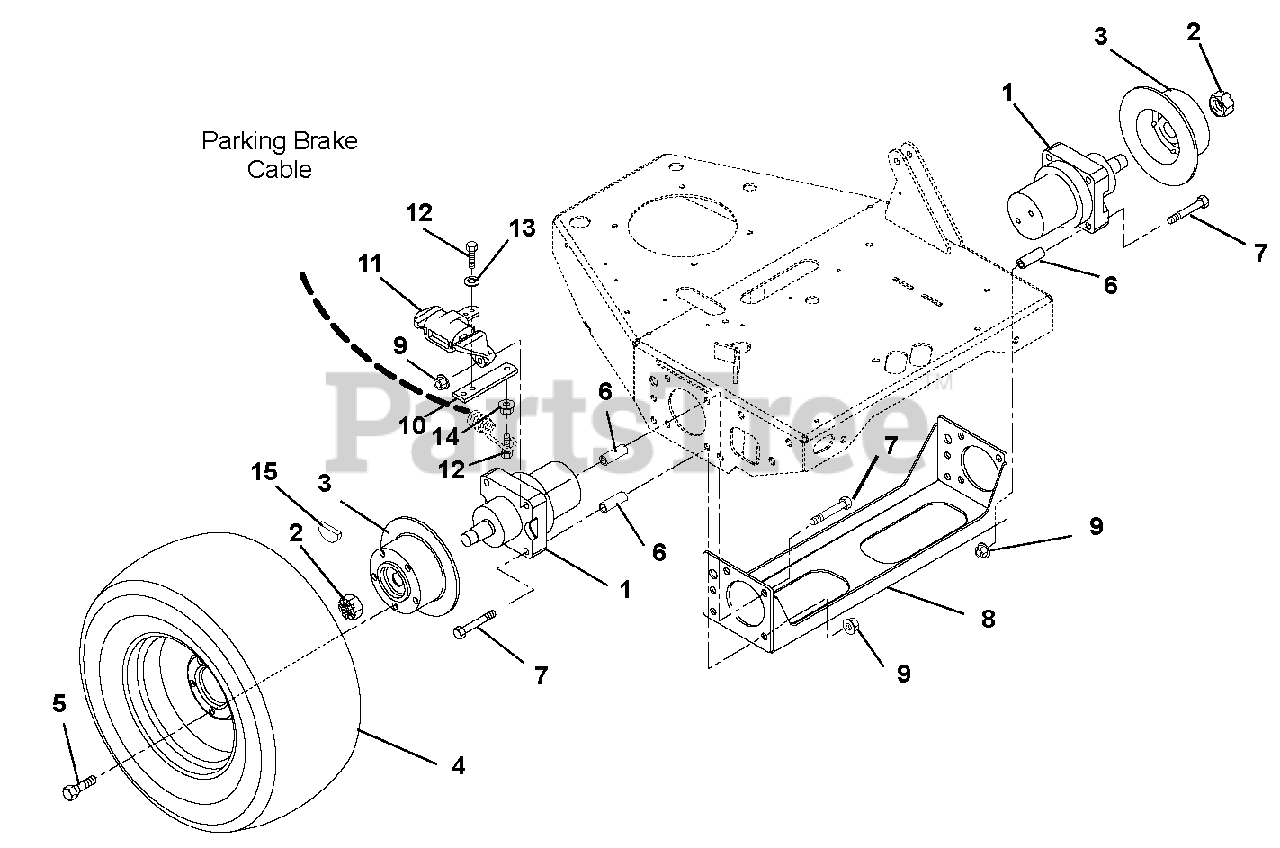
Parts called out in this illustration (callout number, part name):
1	Motor, Hydraulic Wheel (Includes 2)
2	Nut, Locking-Jam-Patch 1.00-20 (Included with 1)
3	Hub and Disc
4	Tire/Wheel Assembly 24 x 12-12
5	Bolt, Lug .50-20 x 1.38, Grade 8
6	Bushing-Sleeve .513 x .748 x 2.129
7	Bolt-Hex .50-13 x 5.00 Grade 8
8	Weldment, Wheel Support Bracket
9	Nut-Locking-Top-Flange .50-13
10	Arm, Extension Parking Brake
11	Caliper, Park Brake (Clockwise) Right Hand
12	Bolt-Hex .31-18 x 1.00 Grade 5
13	Washer, Locking .31 x .078
14	Nut-Spin-Locking-Flange .312-18
15	Pad, Disk Brake
